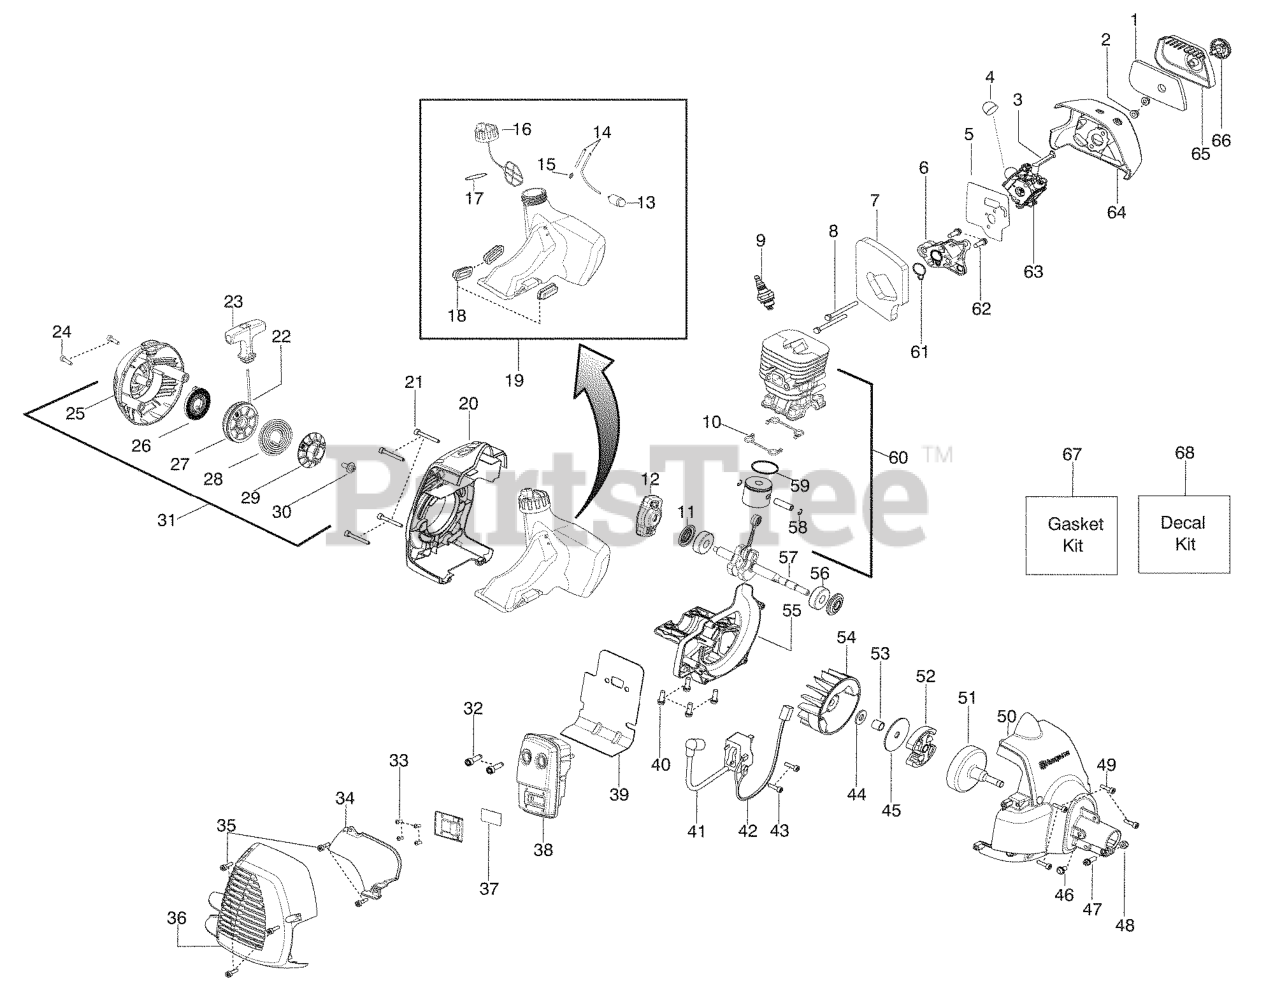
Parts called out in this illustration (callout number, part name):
2	Nut-Carb. Screw
3	Lever - Choke
4	Bulb-Purge
5	Kit-Carb. Gasket
6	Adaptor-Carb.
7	Foam-Gasket
9	Plug-Spark (RCJ-6Y)
10	Seal-Cylinder
11	Seal-Crankshaft
12	Assy-Starter Pawl
13	Assy-Fuel Filter
14	Kit-Fuel Line
15	Fitting-Fuel Line
16	Assy-Cap w/ret.
17	O-ring - Fuel Cap
18	Isolator-Tank
19	Kit-Fuel Tank Assy.
20	Shroud-Rear
22	Kit-Rope
23	Handle-Starter
25	Starter Hsg. w/eyelet
26	Kit-Spring
27	Kit-Starter Pulley
28	Spring - Driver
29	Pulley-Driver
31	Assy-Starter Hsg.
32	Bolt-Muffler
33	Screw
34	Shield-Heat
36	Guard-Muffler
37	Kit-Spark Arrestor
38	Kit-Muffler
39	Gasket-Paper Met.
41	Module
42	Assy-Leadwire
45	Washer-Clutch
50	Assy-Fan Housing
51	Assy-Clutch Drum
52	Assy-Clutch
55	Crankcase-Cast
57	Assy-Crankshaft
58	Retainer-Piston Pin
59	Ring-Piston
60	Kit-Piston/Cyl.
61	Seal-adaptor
63	Kit-Carb.
64	Air box
65	Cover-Air Box
67	Kit-Gasket
